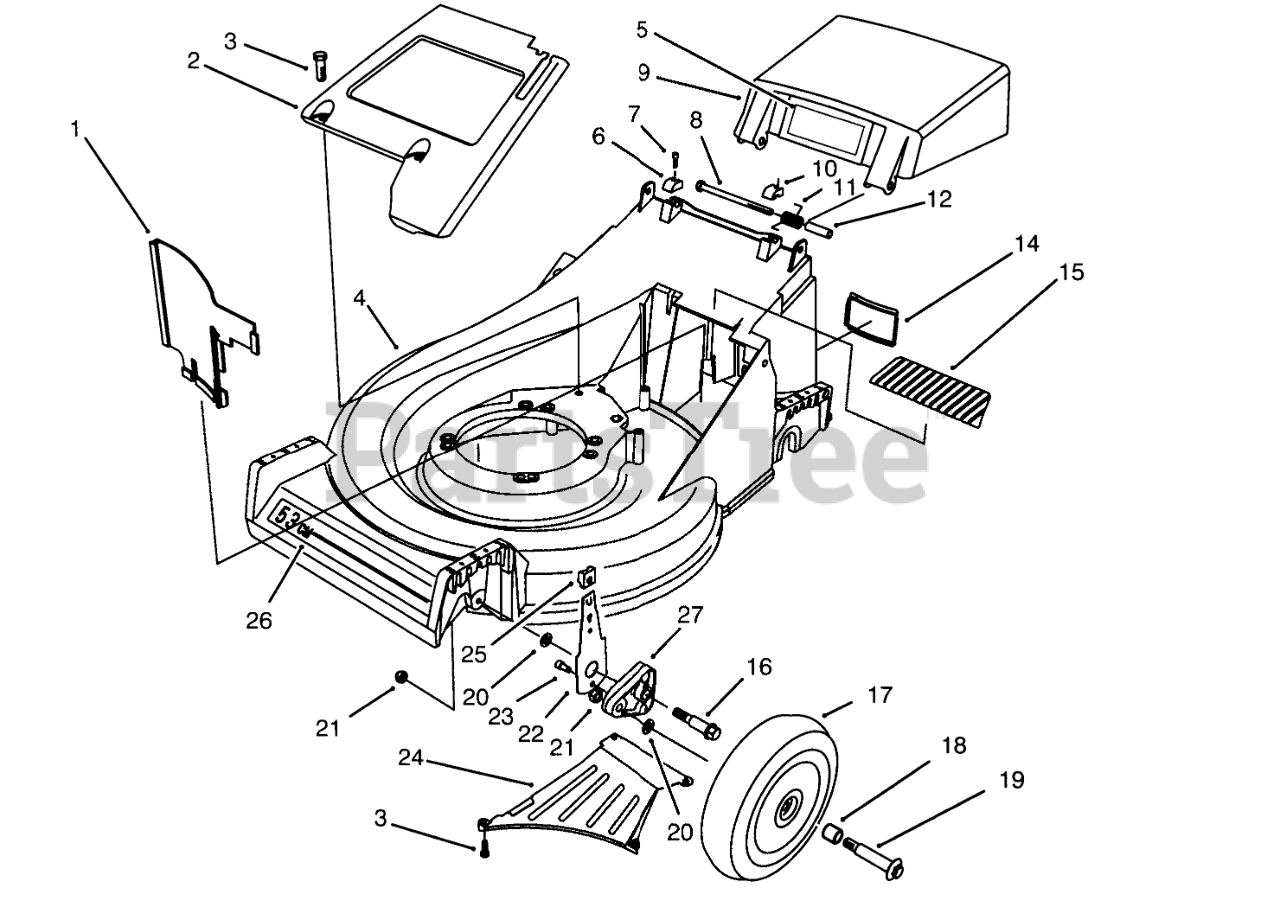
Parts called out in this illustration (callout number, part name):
1	PANEL-VERTICAL
2	PaneI-Screen
3	SCREW-HWHTF
4	Housing-53cm (Incl. Ref. #26)
5	DECAL-DANGER
6	CAP-HINGE BOLT, RH
7	SCREW-HSH
8	SCREW-HH
9	Door Discharge
10	CAP-HINGE BOLT, LH
11	SPRING-DOOR
12	SPACER-DOOR
14	COVER-ACCESS
15	COVER-TOP
16	BOLT-SHOULDER
17	Wheel & Tire Assembly (Incl. Ref. #18)
18	BUSHING
19	WHEEL BOLT
20	WASHER
21	NUT-LOCK
22	FRONT SPRING ARM ASM
23	SCREW-HSH, THREAD FORMING
24	Ramp-Discharge
25	KNOB-ARM
26	DECAL
27	ARM-PIVOT, FRONT
